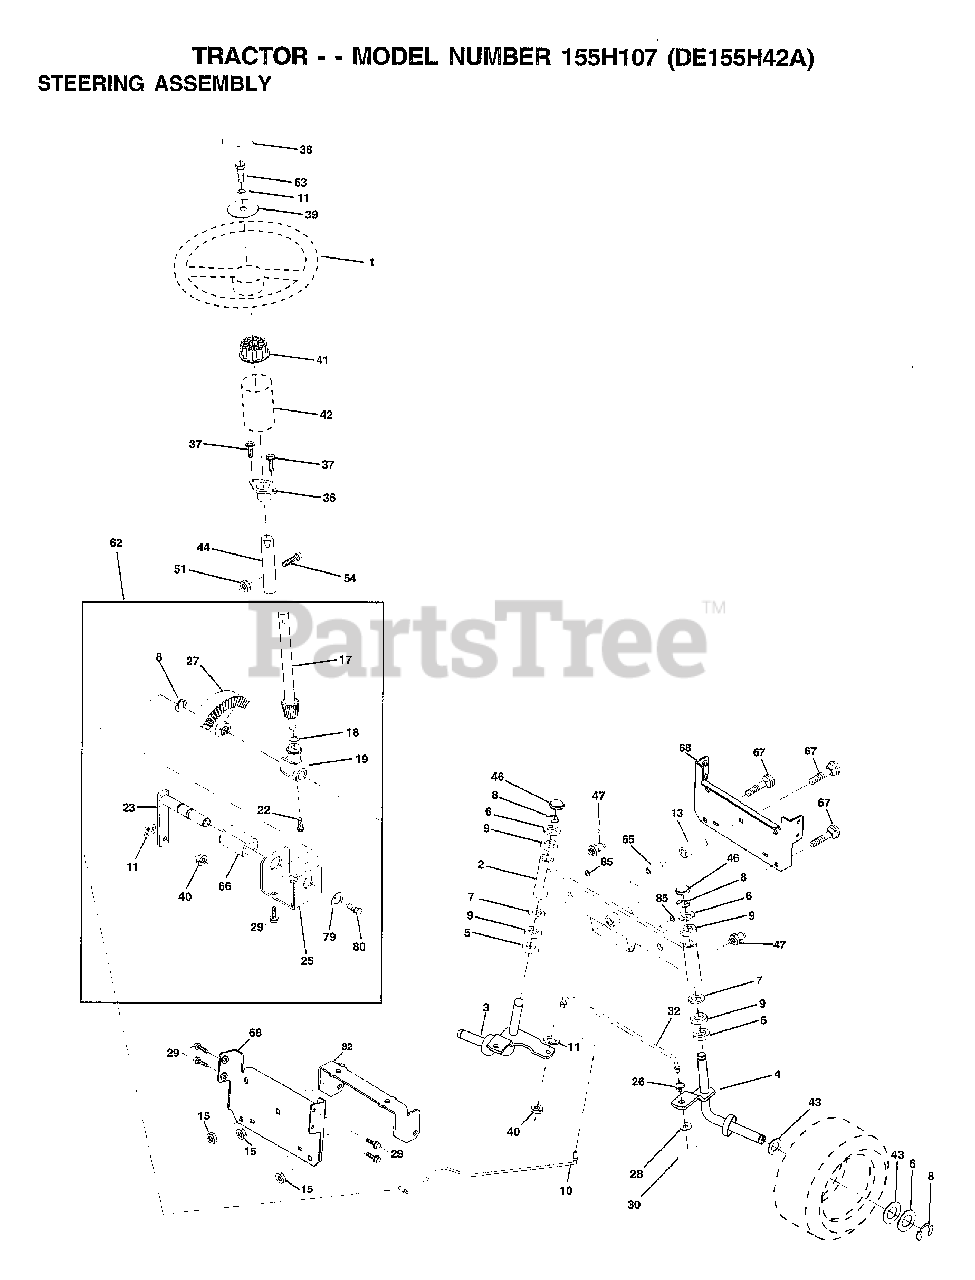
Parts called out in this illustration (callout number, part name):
2	AXLE ASM
3	SPINDLE ASM
4	SPINDLE ASM
5	WASHER .T
6	WASHER
7	WASHER
8	RING
9	COL. SRTG. BEAR.
10	LINK DRAG
11	LOCKWASHER
13	SPACER BEARING
15	NUT.HXFLG.LOCK.
17	SHAFT ASM STEERIN
18	THRUST WASHER
19	SUPPORT.SHAFT.STEER
22	SCREW.HX.WSH.HD
23	SHAFT.ASM.PITMAN
25	BRKT-STEERING
26	BUSHING.DRAGLINK
27	GEAR SECTOR
28	WASHER
29	SCREW
30	COTTER PIN
32	TIE ROD
36	BUSHING.STEERING
37	"SCREW-TT,10-32 FL"
38	CAP WHEEL STEER
39	WASHER
40	GRIPCO NUT
41	ADAPTER LT
42	BOOT.STEERING.DASH.P/L
43	WASHER
44	EXT SHAFT STEERIN
46	CAP
47	ZERK M
51	NUT
54	BOLT
62	KIT.STEER.ASM
63	BOLT
65	"SPACER BRCAE,AXLE"
66	"BEARING-ARM,PITMA"
67	BOLT RDHD 3/8-16
68	BRACE AXLE
79	WASHER
80	BOLT.HX.NYLON3/8-16X3/
82	BRKT SUSP CHASSIS FRT
85	XMAS TREE FASTNER
